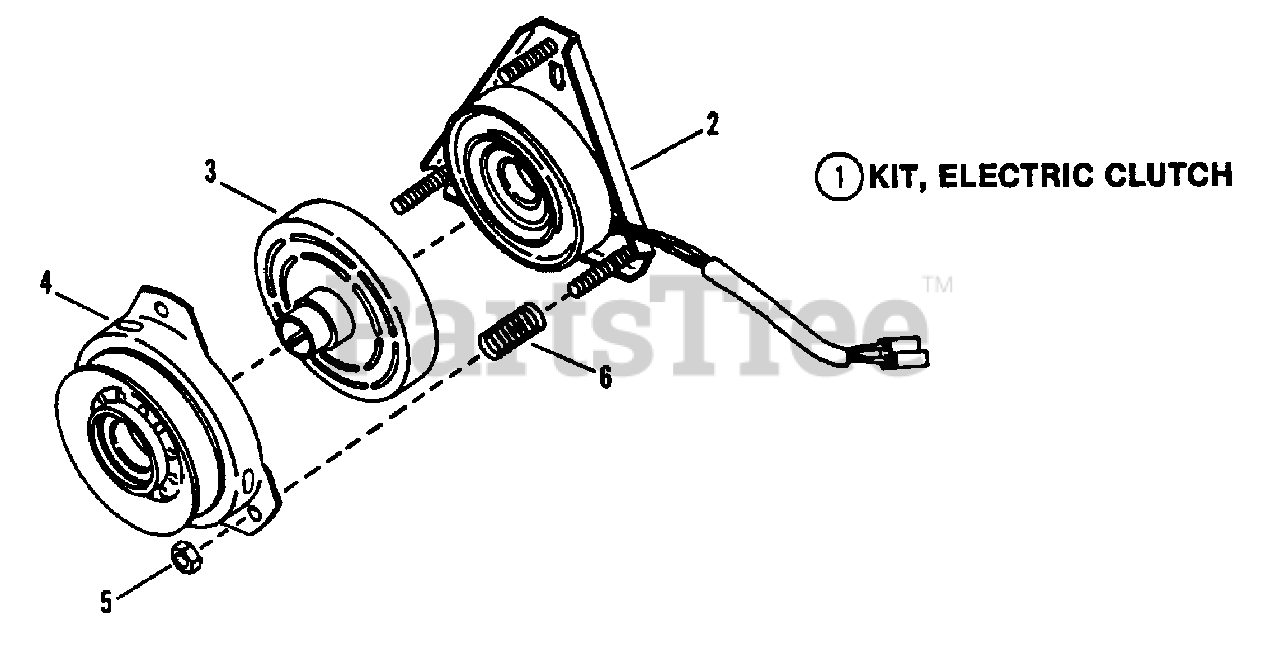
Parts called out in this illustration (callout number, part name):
1	KIT, Electric Clutch
2	FIELD COIL
3	ROTOR
4	ASSEMBLY, Arm-Pulley
5	NUT, 3/8-24 Hex Nyloc
6	COIL SPRING
